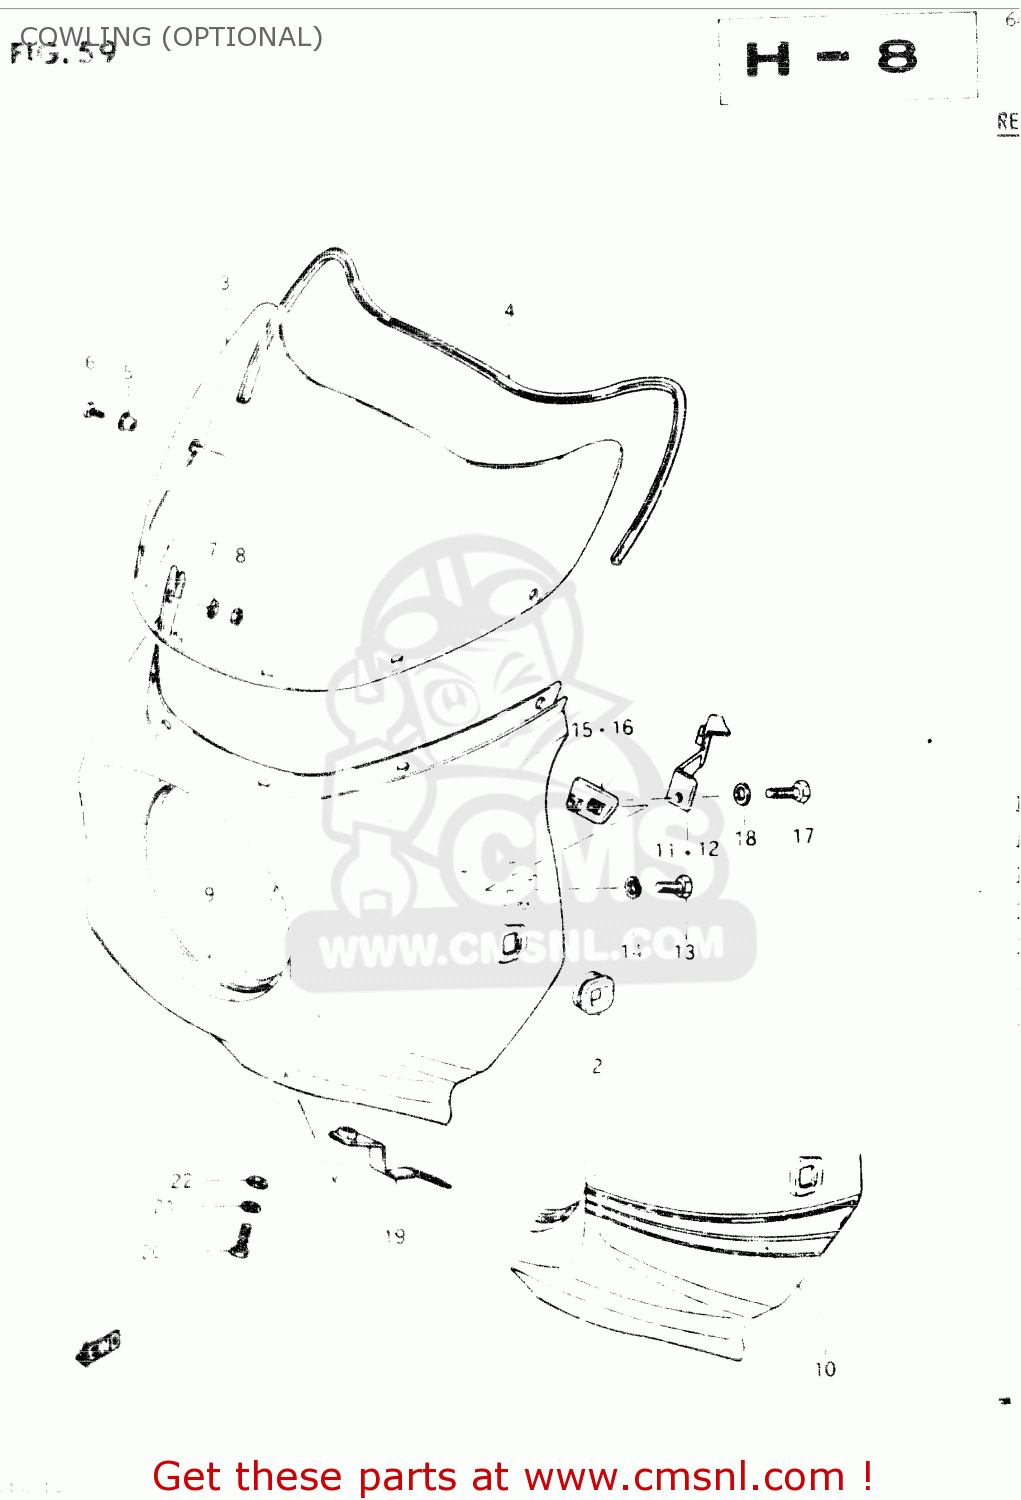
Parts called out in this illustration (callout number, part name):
1	COWLING SET (RED)
2	CUSHION
3	WINDOW
4	MOULDING
5	CUSHION
6	SCREW
7	WASHER,5MM
8	NUT 8MM
9	MOLDING,HEADLAMP GRILL
10	TAPE SET
11	BRACKET,COWLING RH
12	BRACKET,COWLING LH
13	BOLT
14	WASHER,LOCK
15	BRACKET, FITTING RH
16	BRACKET, FITTING LH
17	BOLT 6X16
18	WASHER (6.5X18X1.6)
19	BRACKET, LOWER
20	BOLT
21	WASHER,LOCK
22	WASHER
